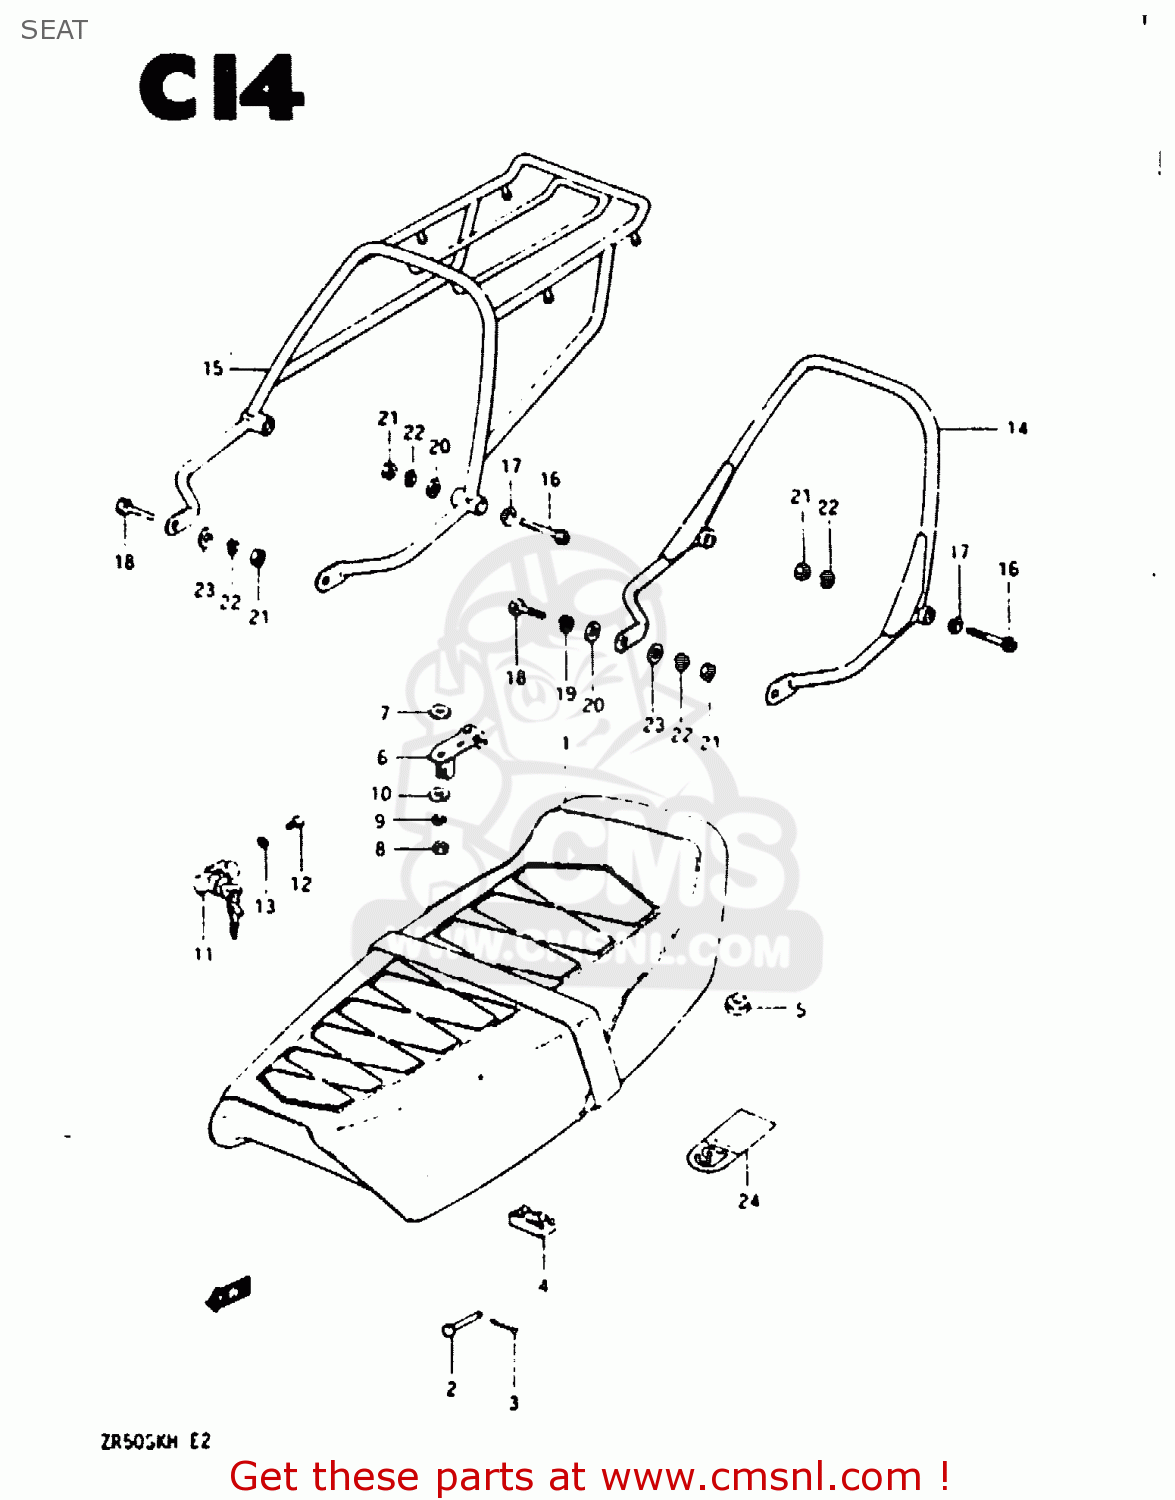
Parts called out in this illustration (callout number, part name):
1	SEAT ASSY (BLACK)
2	PIN
3	PIN
4	CUSHION
5	CUSHION
6	PLATE, SEAT LOCK
7	WASHER(8.5X18X1)
8	NUT
9	WASHER,LOCK
10	WASHER
11	LOCK ASSY,SEAT
12	SCREW
13	LOCK WASHER
14	HANDLE, PILLION RIDER
15	CARRIER, SPORTS
16	BOLT
17	WASHER
18	BOLT 8X50
19	LOCK WASHER
20	WASHER
21	NUT 8MM
22	LOCK WASHER
23	WASHER
24	LABEL,ASBESTOS WARNING
